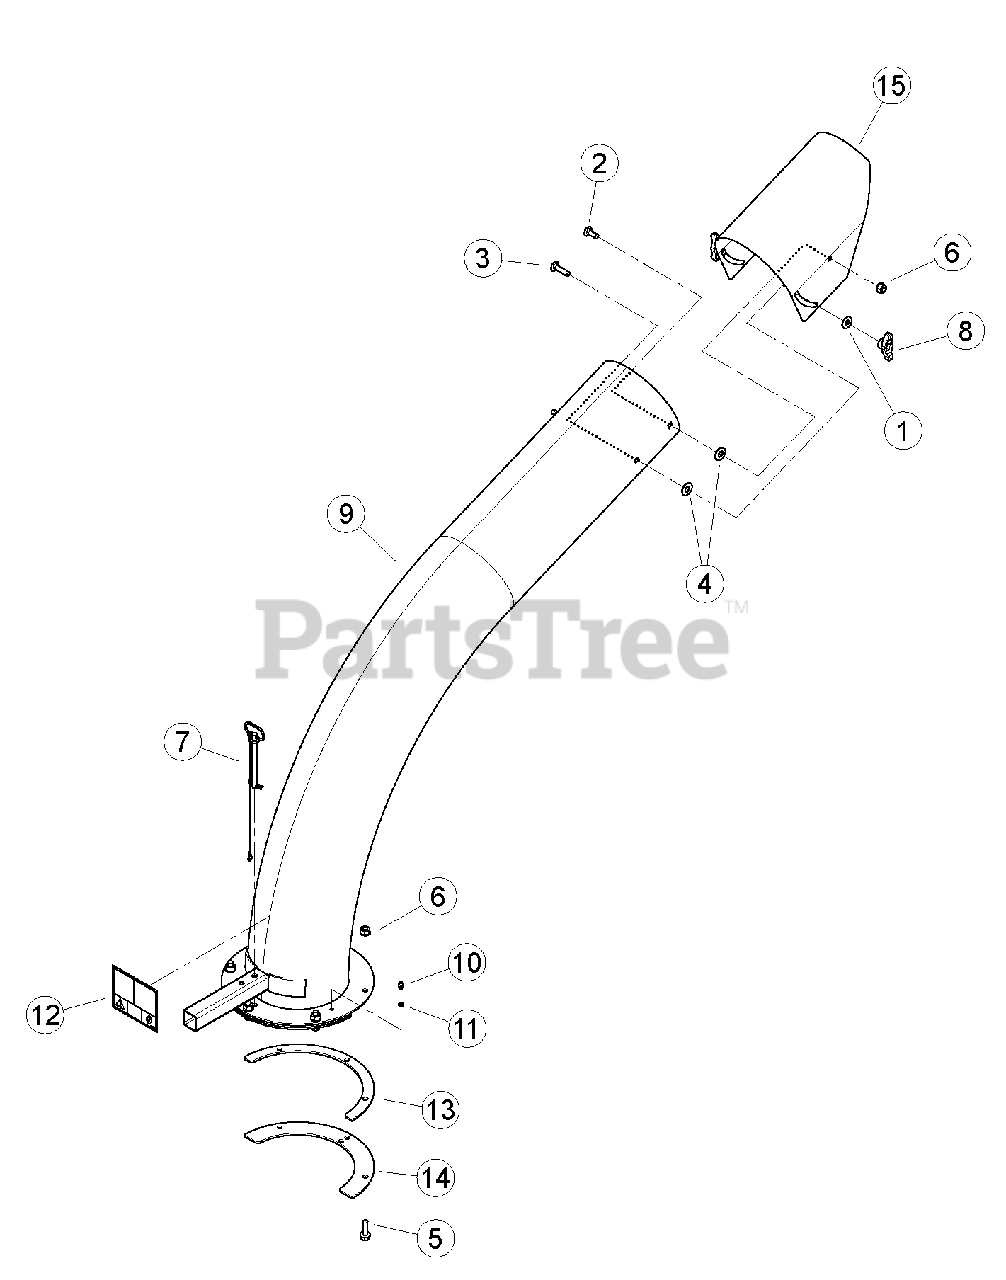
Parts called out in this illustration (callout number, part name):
1	WASHER, 3/8 FLAT
2	BOLT, 3/8-16 X 1 GR5 CRG
3	BOLT, 3/8-16 X 1-1/2 GR5 CRG
4	WASHER, 1/2 SAE FLAT
5	BOLT, 3/8 X 1-1/4 FLANGE NC
6	NUT, 3/8-16 NYLOCK FLANGE
7	PIN, 3/8 X 4.25" DISCHARGE
8	KNOB, 3/8-16 UNC FEMALE TEE
9	ASSEMBLY, 8 INCH DISCHARGE CHUTE
10	FITTING, 1/4 SELF-TAP GREASE
11	WASHER, FLAT .254 X .400 X .048
12	DECAL, DISCHARGE DEBRIS & LOCK
13	RING, DISCHARGE SPACER
14	RING, DISCHARGE CLAMP
15	CAP, 8 INCH DISCHARGE CHUTE
